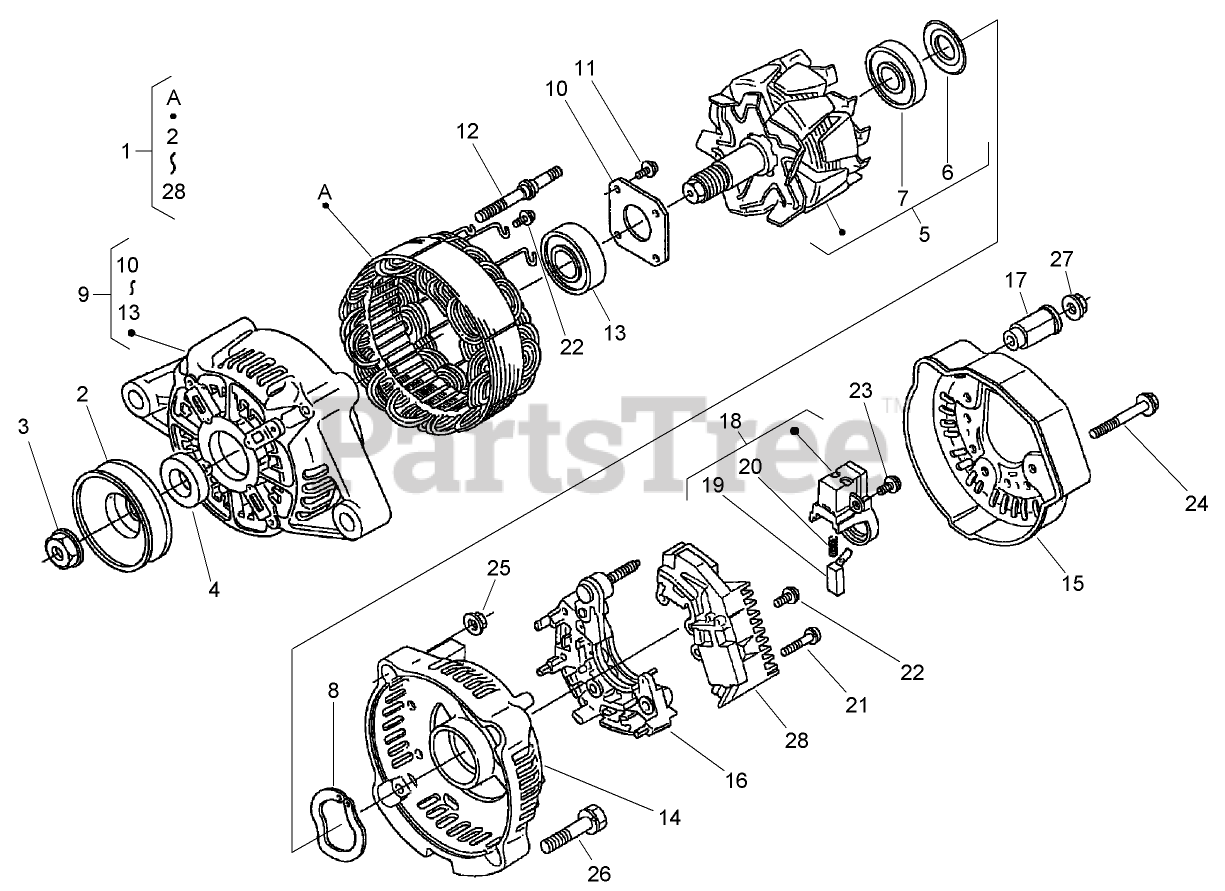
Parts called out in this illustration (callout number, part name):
1	ALTERNATOR ASM
2	PULLEY-DYNAMO
4	COLLAR
5	Rotor ASM
6	COVER-BEARING
7	Bearing-Ball
8	WASHER-THRUST
9	Drive End Frame ASM
10	PLATE-RETAINER
11	SCREW-HEAD, ROUND
12	BOLT-THROUGH
13	Bearing-Ball
14	FRAME-END
15	Cover-End
16	RECTIFIER ASM
17	BUSHING-INSULATION
18	Brush Holder ASM
19	BRUSH
20	SPRING-BRUSH
21	SCREW-HEAD, ROUND
22	SCREW-HEAD, ROUND
23	SCREW-HEAD, ROUND
28	REGULATOR ASM
